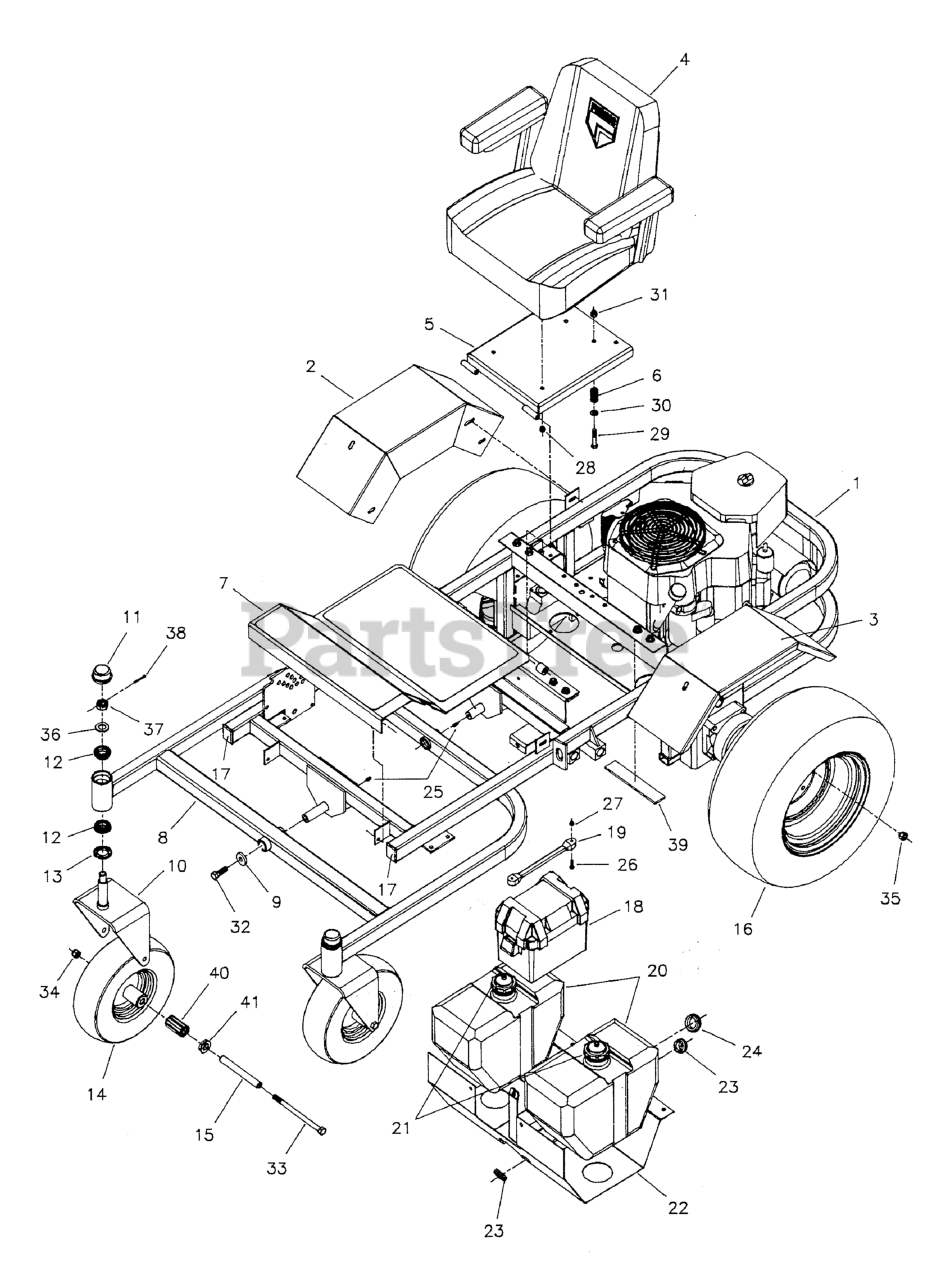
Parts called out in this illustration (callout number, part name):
1	FRAME, Main
2	FENDER, Right
3	FENDER, Left
4	SEAT, GRAY, NO LOGO, CMPT
5	SEAT, Plate
6	SPRING, Compression
7	FLOOR PLATE ASSEMBLY
8	FRAME, Front Pivot
9	WASHER, Frame Retaining
10	YOKE, Caster
11	CAP
12	BEARING, Tapered Roller
13	SEAL, GREASE
14	WHEEL & TIRE ASSEMBLY, 13 x 5.0 x 6, Complete
15	SHAFT, Caster Axle
16	WHEEL & TIRE ASSEMBLY, 23 x 10.5-12, White, Complete
17	CAP, Plastic
18	BOX, Battery
19	RUBBER STRAP
20	FUEL TANK, 4 Gallon
21	CAP, Fuel Tank
22	MOUNT, Fuel Tank
23	GROMMET, 7/8"
24	GROMMET, 1-1/4"
25	GREASE FITTING
26	SCREW, #10-24 X 1 RS, CZ
27	NUT, #10-24 Hex Nylon Lock
28	NUT, 5/16-18 Hex Nylon Lock
29	BOLT, 3/8-16 X 2-1/4" GD5 CZ
30	WASHER, 3/8 SAE
31	NUT, 3/8-16 HEX NYLON LOCK
32	BOLT, 1/2-20 X 1-1/4" GD5 CZ
33	BOLT, 1/2-13 x 7-1/2
34	NUT, 1/2-13 HEX NYLON LOCK
35	LUG NUT, 1/2-20
36	WASHER, 3/4 SAE
37	NUT, 3/4-16 Hex Slotted
38	PIN, COTTER, 1/8 X 1-1/4
39	RUBBER PAD
40	BEARING, Roller
41	RETAINER, Bearing
44	SPRING, EXTENSION, SEAT ADJUSTMENT (YEL OR BLK)
